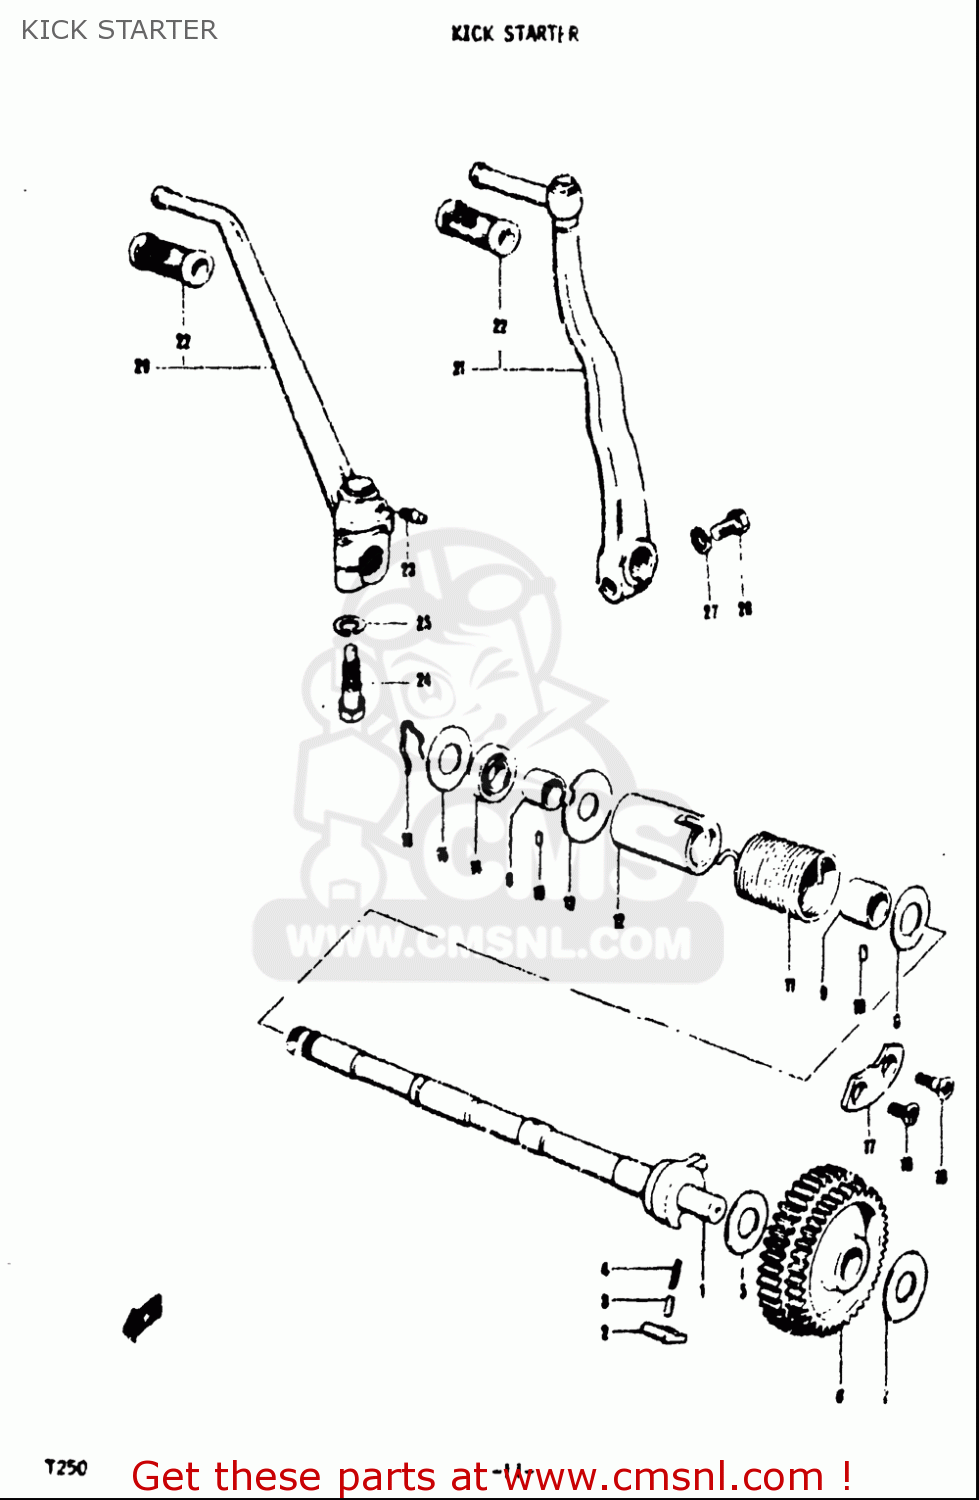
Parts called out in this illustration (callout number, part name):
3	PIN(5X15.5)
4	SPRING
5	WASHER(13X31.5X1.5)
7	WASHER(13X31.5X1.5)
8	WASHER(16X30X1)
10	PIN
11	SPRING
18	SCREW(6X19)
19	SCREW
22	RUBBER,KICK STARTER PEDAL
23	NIPPLE
24	BOLT(10X37.5)
25	WASHER,LOCK
26	BOLT
27	WASHER,LOCK
